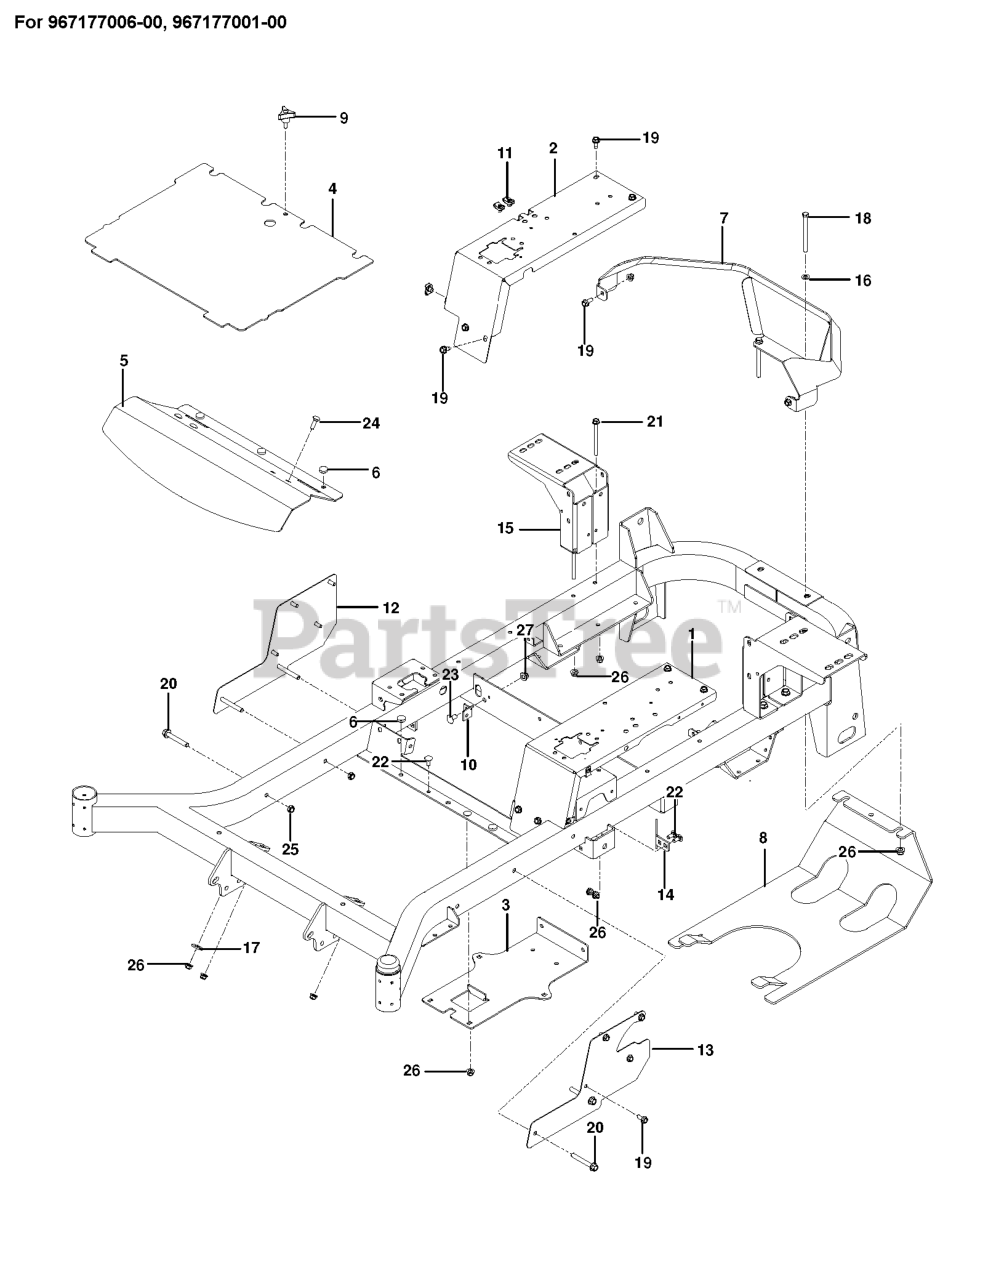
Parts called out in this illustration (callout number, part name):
1	PANEL.FILLER.LT.ORANGE
2	PANEL.FILLER.RT.ORANGE
3	PLATE, BATTERY, BLACK
4	PLATE, FLOOR W/DECALS
5	PLATE, FOOTREST
6	GROMMET, BUMPER
7	GUARD, REAR MZ, GRAY
8	GUARD SKID PNT 498
9	KNOB W/STUD
10	BRACKET.DAMPENER.BLACK
11	U-CLIP 5/16-18 NUT RETAINER
12	SIDE RIGHT BLACK
13	SIDE LEFT BLACK
14	STOP, DECK, EZ+
15	MOUNT, TANK, ZT BLK
16	FLAT WASHER 5/16 SAE
17	WASH USS FLAT 1/2
18	HCS 5/16C X 4
19	HHFS 5/16-18 X 3/4
20	HHFS 3/8-16 X 2 3/4
21	HHFS 5/16-18 X 3 3/4
22	BOLT 5/16C X 3/4" CARRIAGE
23	RHSNB 3/8-16 X 3/4 GR 5 BLK ZN
24	RHSNB 5/16C X 1
25	NUT HEX 3/8-16 NYLON, THIN
26	5/16-18 NYLOC FLANGE NUT
27	NUT 3/8-16 HEX FLG NYLOC ZD
